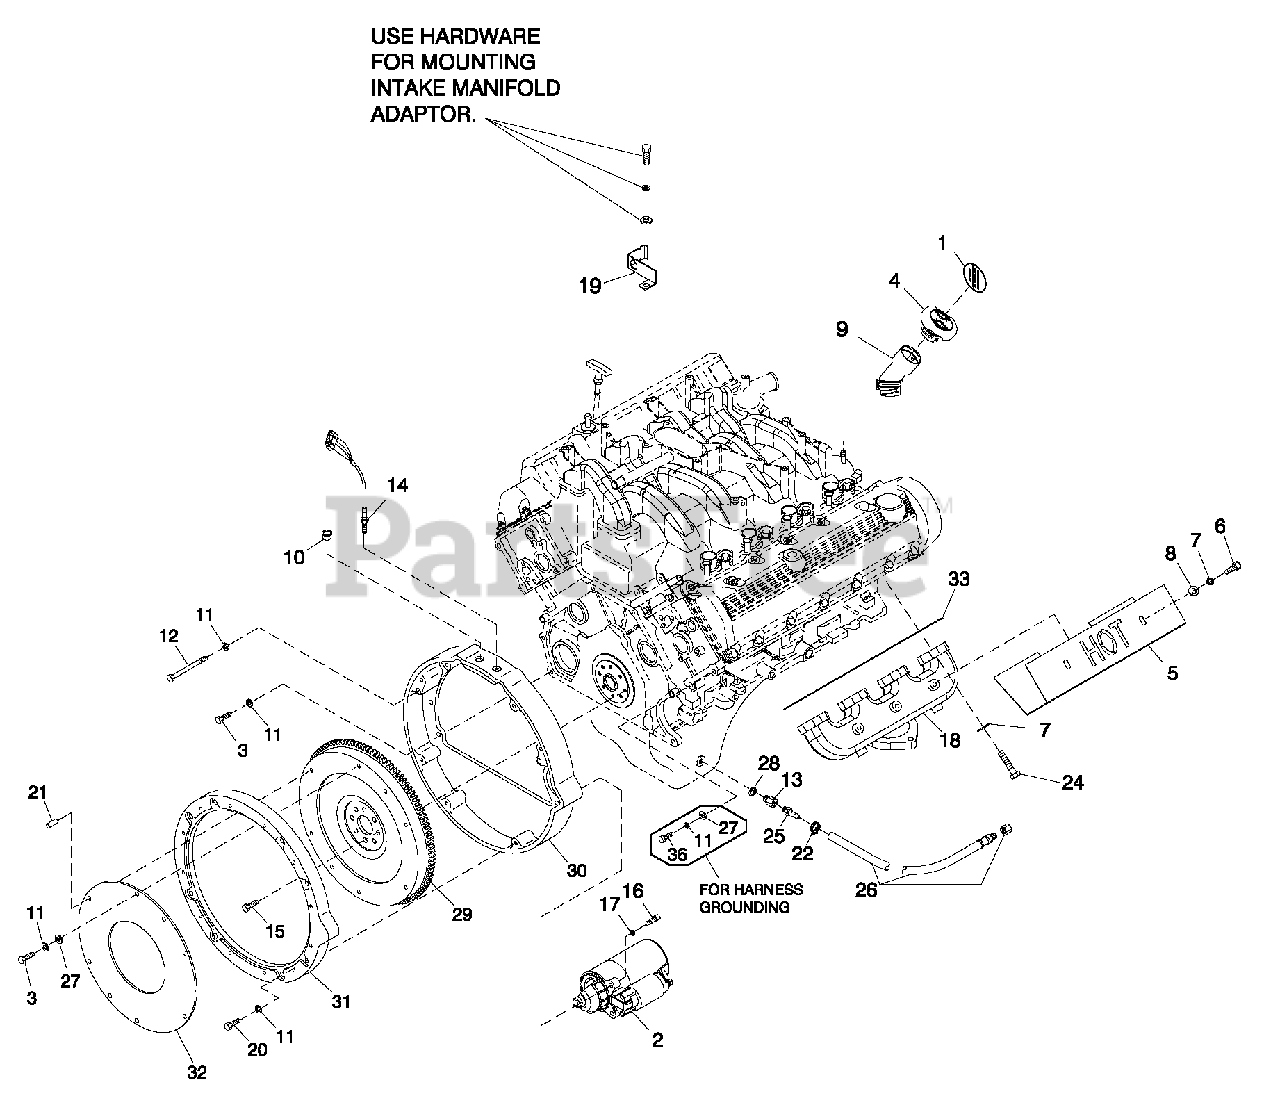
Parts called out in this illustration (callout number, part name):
1	DECAL REFER TO OWNERS MANUAL
2	STARTER MOTOR V-10 G3 ENGINE
3	SCREW SHC M10-1.5 X 35 G12.9
4	CAP OIL FILLER
5	HEAT SHLD EXHAUST MANIFOLD
6	SCREW HHC 5/16-18 X 1/2 SSTL
7	WASHER LOCK M8 SSTL
8	WASHER FLAT M8 SS
9	NECK OIL FILLER
10	PLUG PLASTIC 3/8 NPT
11	WASHER LOCK M10
12	SCREW SHC M10-1.50 X 100 G10.9
13	ADAPTER M14-1.50X 3/8 NPT
14	ASSY MAGPICKUP(3/8-24 MALE)
15	SCREW HHC M10-1.0 X 25 G10.9
16	SCREW SHC M8-1.25 X 30 G12.9
17	WASHER LOCK M8-5/16
18	MACHINED MANIFOLD EXHAUST 5.4L
19	BRACKET SIGNAL CONDITIONER
20	SCREW SHC M10-1.5 X 25 G12.9
21	DOWEL PINM10X24
22	CLAMP HOSE .38-.87
24	SCREW SHC M8-1.25X 35 SS
25	BARBED STR 3/8 NPT X 3/8
26	HOSE DRAIN ASSY 28"
27	WASHER FLAT 3/8-M10 ZINC
28	WASHER NYLON .565
29	ASSEMBLY 6.8L G-BOX FLYWHEEL
30	FLYWHEEL HOUSING MACH 6.8L V10
31	COVER FLYWHEEL MACH 6.8L V-10
32	PLATE DAMPNER RETNR
33	GASKET, EXHAUST MANIFOLD
